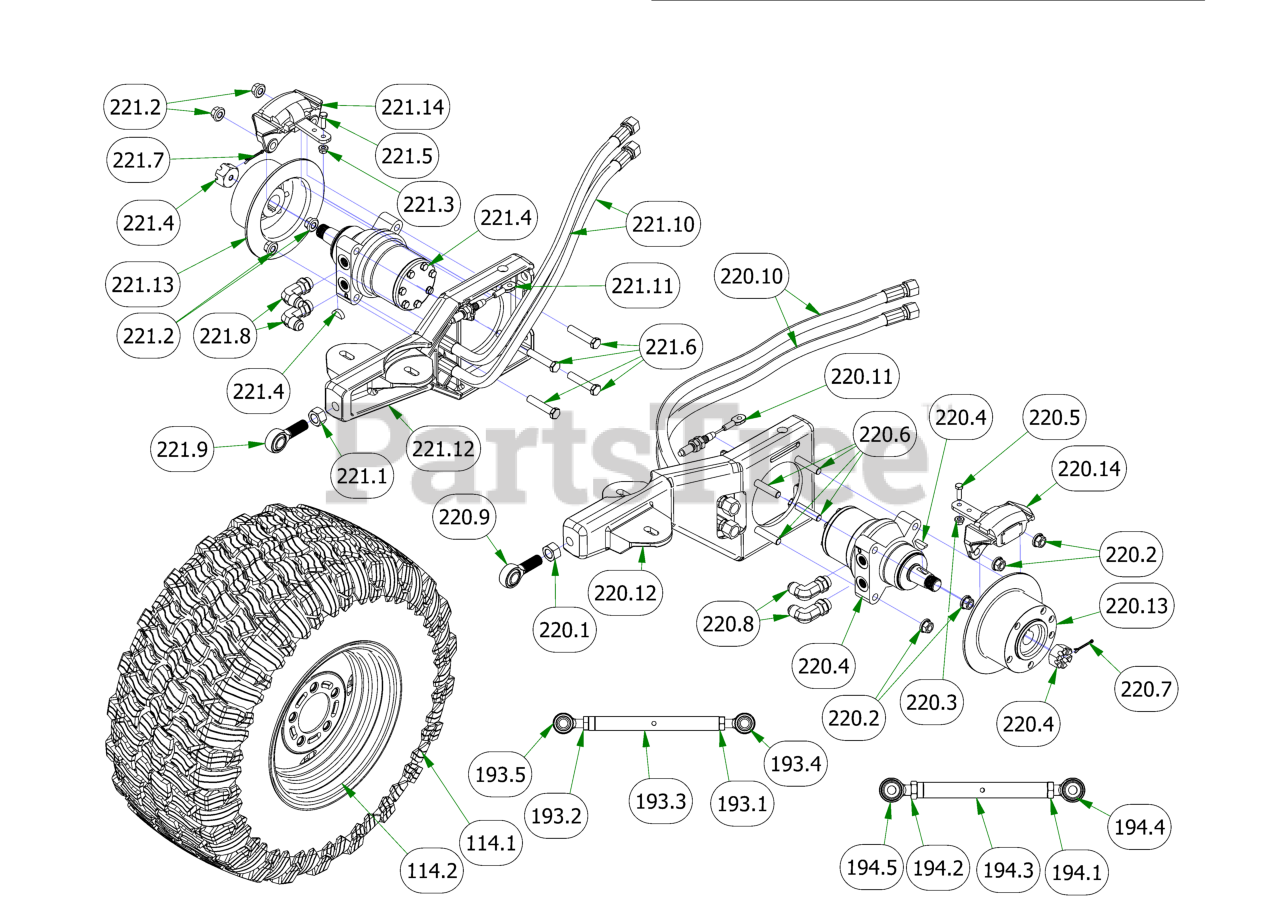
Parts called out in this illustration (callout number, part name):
114	2019 Assy-26x12-12 Reaper Turf -10.5" Rim
114.1	2019 26x12-12 Reaper Turf Tire
114.2	2019 10.5" Wheel
193	2019 Suspension Radius Rod Assembly
193.1	5/8-11 HEX JAM NUT ZINC
193.2	NUT, 5/8-18LH
193.3	2019 Suspension Link Body
193.4	2019 RH 5/8" Heim
193.5	2019 LH 5/8" Heim
194	2019 Suspension Radius Rod Assembly
194.1	3/4-16 HEX JAM NUT ZINC
194.2	3/4-16 LH HEX JAM NUT ZINC
194.3	Rear Radius Rod, 3/4 Body
194.4	3/4-16 x 5/8 RH Heim
194.5	3/4-16 x 5/8 LH Heim
220	2019 Renegade Trailing LH Arm Assy
220.1	3/4"-16 Fine Full Nut
220.2	1/2-13 Gr 8 Centerlock Flange Nut
220.3	5/16-18 NYLON INSERT FLANGE LOCKNUT ZINC
220.4	18cc Parker Wheel Motor- Left
220.5	5/16-18 X 1 HEX CAP SCREW (GR.5) ZINC
220.6	1/2-13 x 2.75 Gr. 8 Hex Head Bolt
220.7	1/8 X 1-1/2 COTTER PIN ZINC
220.8	2019 Rouge/Renegade Wheel Motor 90* Fitting #6801-10L
220.9	3/4-16 RH Male Rod End
220.10	2019 Renegade Hydro Hose
220.11	2019 Short Brake Cable-Suspension Models
220.12	2019 Left Trailing Arm
220.13	Brake Disk
220.14	XP/AOS Left Brake Caliper
221	2019 Renegade Trailing RH Arm Assy
221.1	3/4"-16 Fine Full Nut
221.2	1/2-13 Gr 8 Centerlock Flange Nut
221.3	5/16-18 NYLON INSERT FLANGE LOCKNUT ZINC
221.4	18cc Parker Wheel Motor- Right
221.5	5/16-18 X 1 HEX CAP SCREW (GR.5) ZINC
221.6	1/2-13 x 2.75 Gr. 8 Hex Head Bolt
221.7	1/8 X 1-1/2 COTTER PIN ZINC
221.8	2019 Rouge/Renegade Wheel Motor 90* Fitting #6801-10L
221.9	3/4-16 RH Male Rod End
221.10	2019 Renegade Hydro Hose
221.11	2019 Long Brake Cable-Renegade, Rogue
221.12	2019 Right Trailing Arm
221.13	Brake Disk
221.14	XP/AOS Right Brake Caliper
